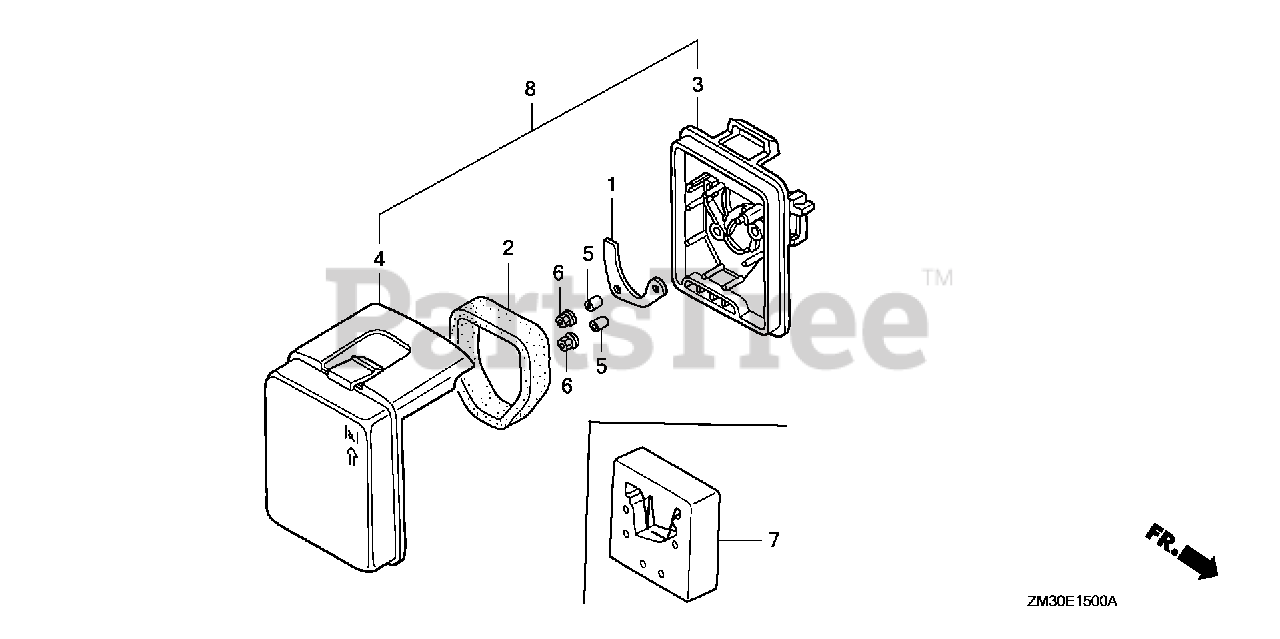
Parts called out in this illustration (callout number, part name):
1	PLATE, OIL TRAP
2	ELEMENT, AIR CLEANER
3	HOUSING, AIR CLEANER *R291R* (DARK POWER RED)
4	COVER, AIR CLEANER *R280* (POWER RED)
4	COVER, AIR CLEANER *R291R* (DARK POWER RED)
5	COLLAR, AIR CLEANER
6	NUT, FLANGE (5MM)
